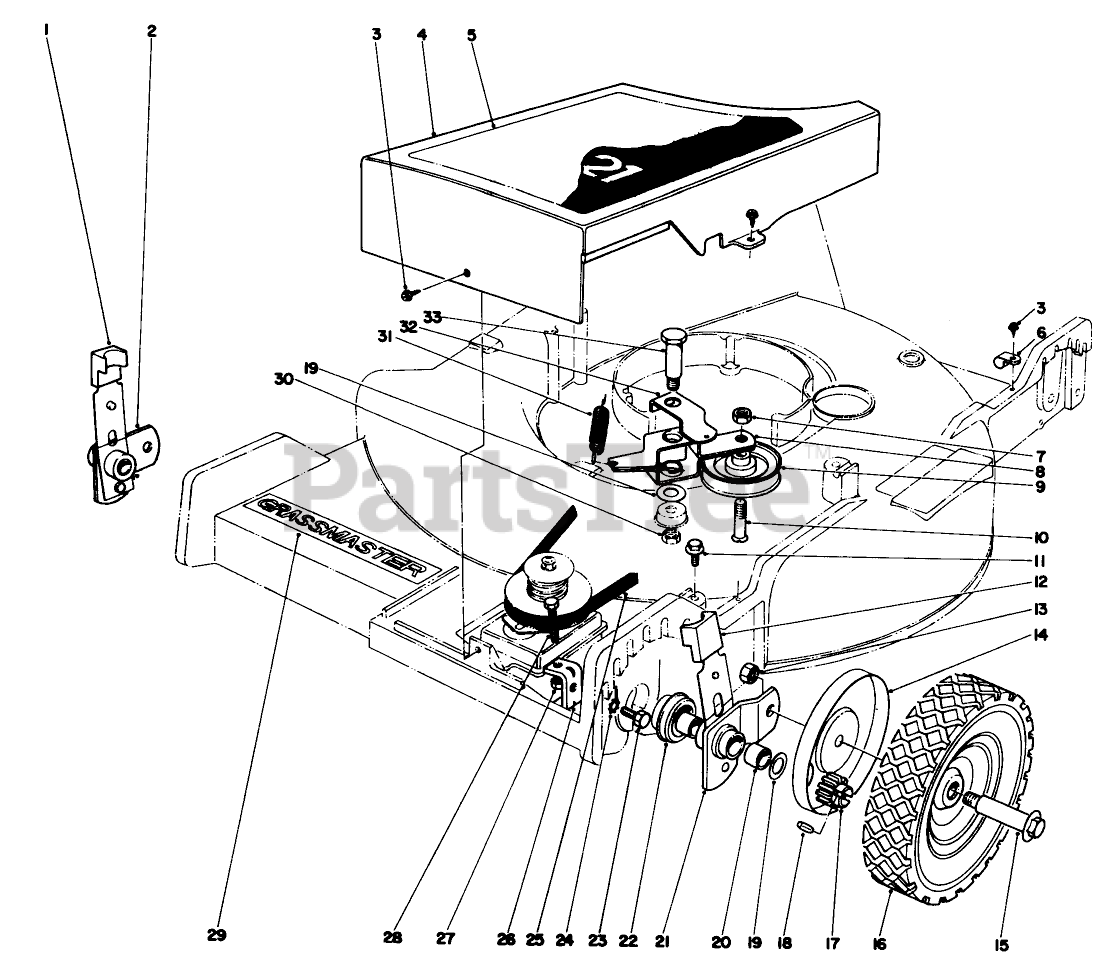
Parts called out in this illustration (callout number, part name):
3	SCREW-HWHTF
5	Decal Belt Cover
6	CLAMP-NYLON
7	NUT-HEX
8	Idler Bracket
10	Screw Low Head
11	SCREW-THD ROLL, HWH
12	Arm Knob
18	PIN-GROOVED
19	WASHER-THRUST
20	BUSHING
23	SCREW-HH
24	WASHER-LOCK
25	V-BELT
26	Bracket
27	NUT-JAM
28	Screw
29	Decal Grassmaster
32	Idler Bracket Lever
33	SCREW-SHOULDER, HH
